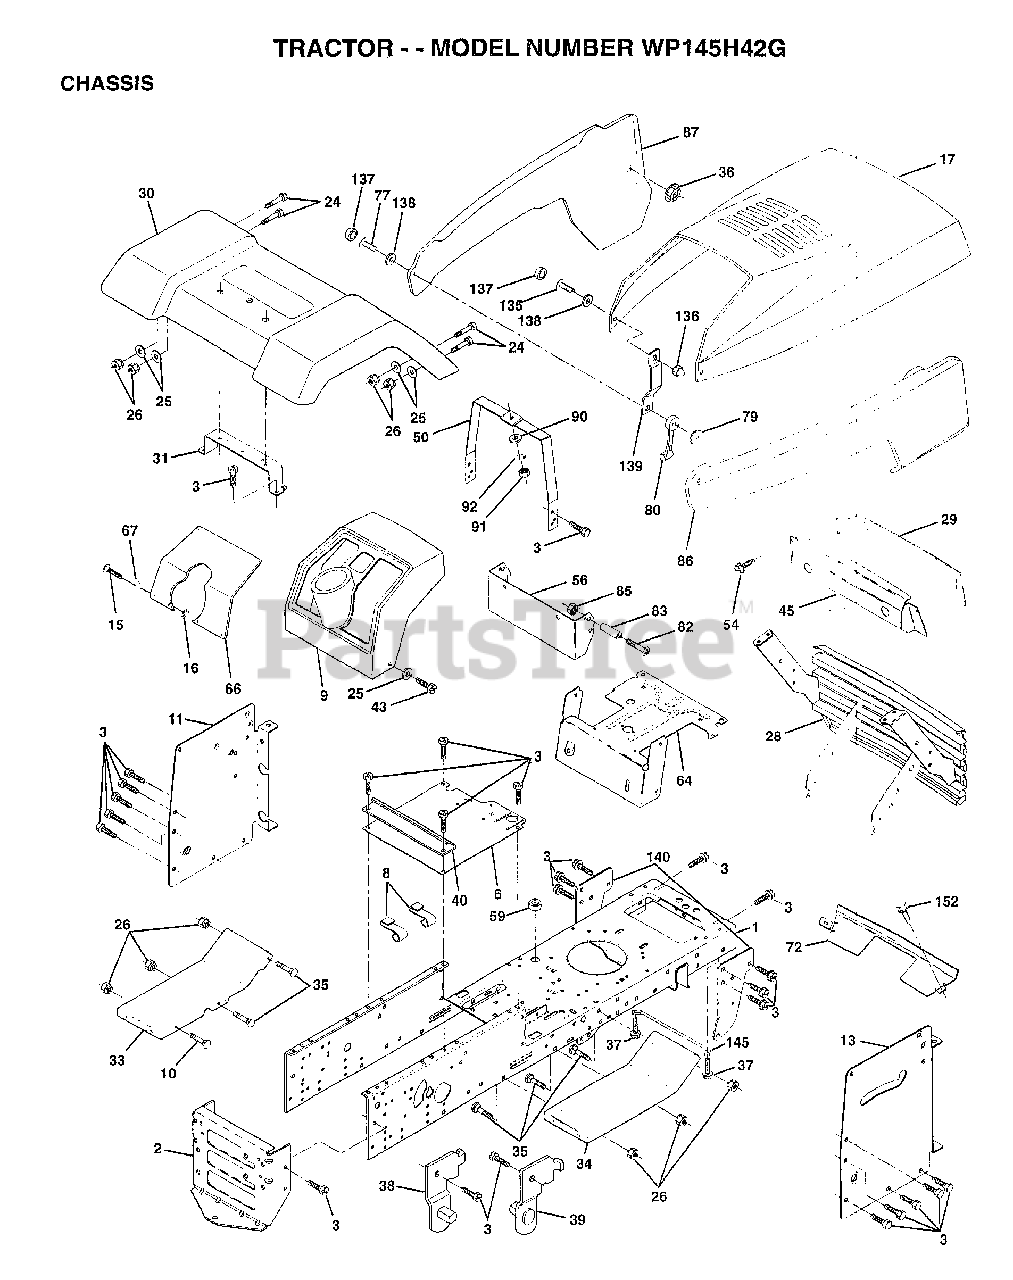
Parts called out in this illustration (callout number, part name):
1	CHASSIS.STAMPING
3	SCREW
6	SADDLE
8	"CLIP,INSULATOR"
9	DASHBOARD BLACK
11	PANEL.DASH.LH.
13	PANEL.DASH.RH.
15	SCREW
24	BOLT
25	WASHER
26	NUT
28	GRILLE ASM PNT
29	LENS.BAR.CLEAR
30	FENDER.LTST.WLDMNT.W/SHIFT
31	BRACKET SUPT FEND
33	FOOTREST.LH.LT/GT
34	FOOTREST.RH.LT/GT
35	BOLT
36	PAL NUT LT
37	SCREW LT
38	BRACKET ASM LH
39	BRACKET ASM RH
40	SPACER FENDER LT
43	SCREW GTV
45	BEZEL.1 PC
50	DASH.SUPT.YP/HUSQ
54	SCREW.HEX.WS.HD
56	EXT DASH LTYT
64	DASH.LOWER.LT
67	WASHER
72	STRAP.GRILLE.PNT.
77	SCREW
79	WELDNUT
80	HOOD LATCH T
82	SCREW
83	SPACER LT
87	"PANEL SIDE,LH"
90	WASHER PM
92	LOCKWASHER
135	SCREW.10-24X3/8.
136	ACORN NUT RB
137	SNAP CAP LT
138	WASHER LT
139	BKT.SPT.HOOD/PANL
140	BRKT SUSPENSION
145	"ROD POVOT,CHASSIS"
152	SCREW
